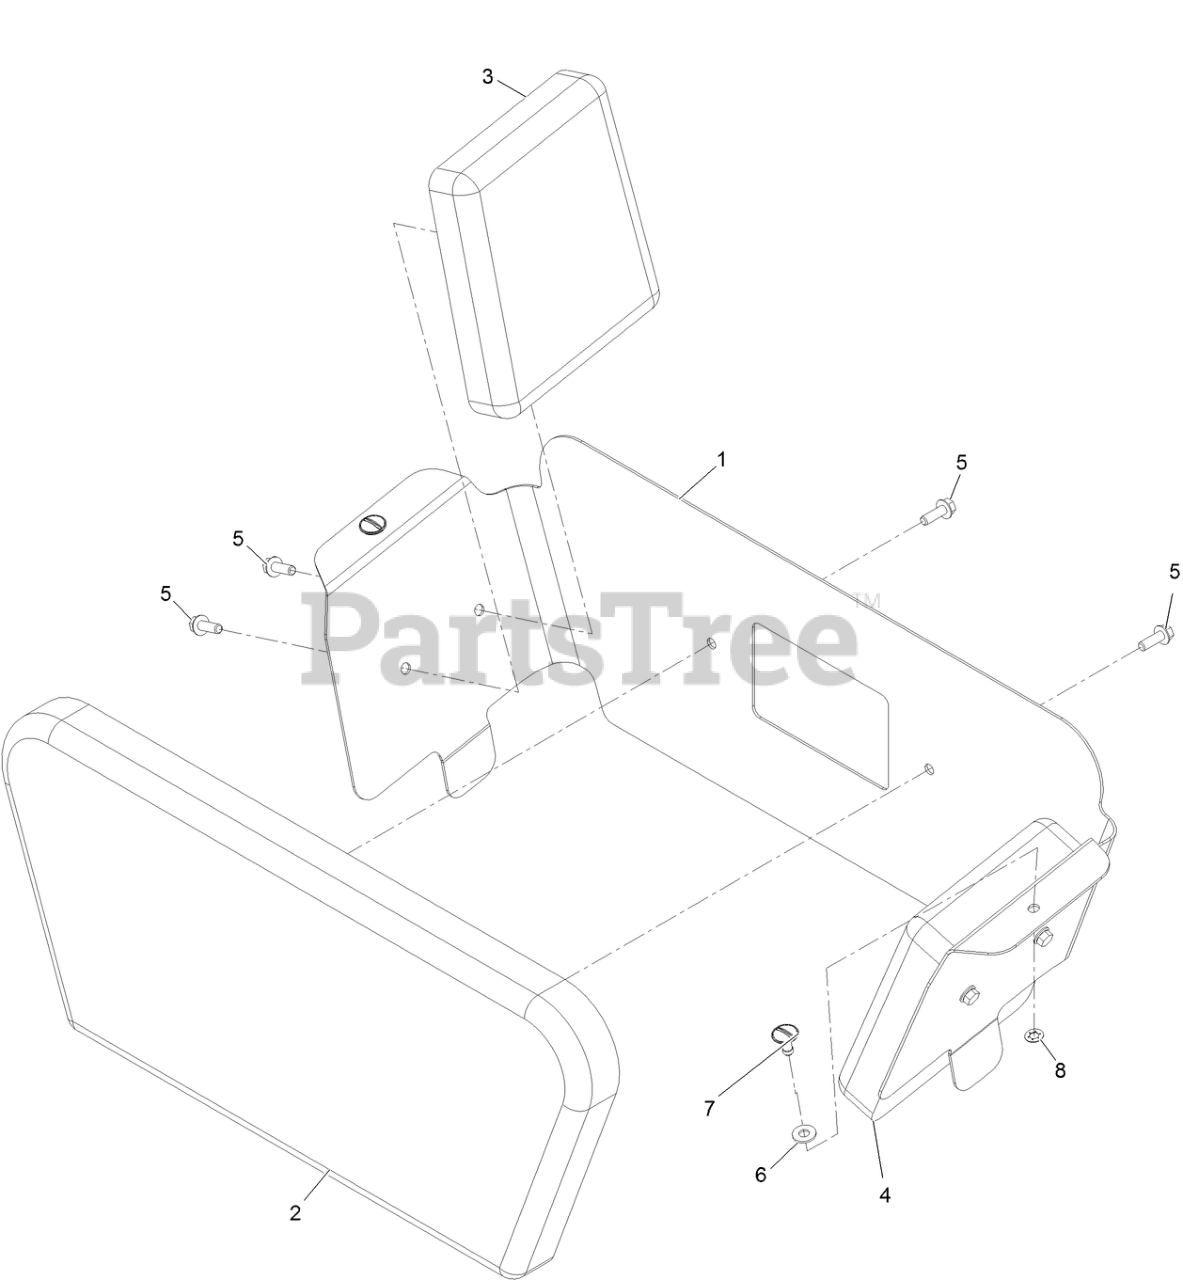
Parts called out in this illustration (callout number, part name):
1	BRACKET-PAD, KNEE
2	Pad-Knee, Center
3	PAD-KNEE, LH SIDE
4	PAD-KNEE, RH SIDE
5	SCREW-HHF
6	WASHER-FLAT
7	STUD-1/4 TURN
8	RETAINER-STUD
